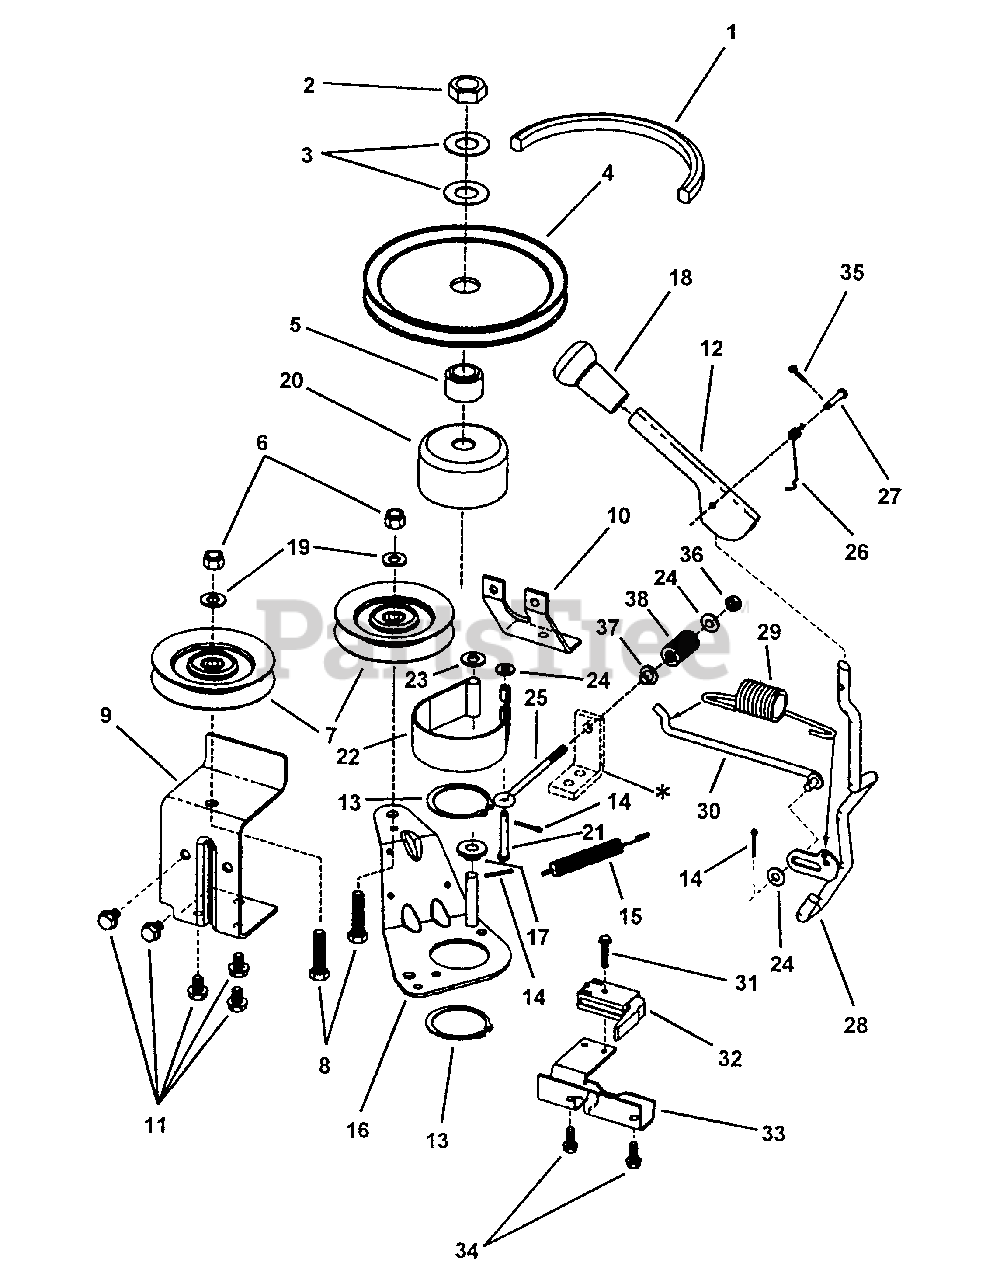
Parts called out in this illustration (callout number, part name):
1	BELT, Drive (73.75" AA Section)
2	NUT, 3/4-16 Hex Jam
3	WASHER, 49/64" I.D. x 1-1/2" O.D. Flat
4	PULLEY, Spindle
5	HUB, Pulley
6	NUT, 3/8-16 Nyloc
7	PULLEY, 4" Idler
8	SCREW, 3/8-16 x 1-1/2" Hex Head Cap, Grade 5
9	BRACKET, Fixed Idler
10	BRACE
11	SCREW, 5/16-18 x 1/2" Hex Washer Self-Tap
12	HANDLE, Blade Engage (Flip)
13	RING, 2" External Retaining
14	PIN, 3/32 x 3/4" Cotter
15	SPRING, Extension, 4" x 1/2" Diameter
16	ARM, Idler
17	SPACER
18	GRIP, Handle
19	WASHER, 3/8" Flat
20	DRUM, Brake
21	PIN, 1/4" x 1-5/8" Clevis
22	BAND, Brake
23	WASHER, 3/8" Flat
24	WASHER, 1/4" Flat
25	EYE-BOLT, 1 /4-20 x 4"
26	SPRING, Flip Handle
27	PIN, 3/16 x 1" Clevis
28	HANDLE, Blade Lever (ON-OFF)
29	SPRING, Blade Handle
30	ROD, Idler
31	SCREW, #10-32 x 1" Hex Washer Self-Tap
32	SWITCH, Deck Interlock
33	MOUNT, Handle
34	SCREW, 1/4-20 x 5/8" Hex Washer Self-Tap
35	PIN, 3/32 x 1/2" Cotter
36	NUT, 1/4-20 Hex Top Lock
37	BUSHING
38	SPRING
